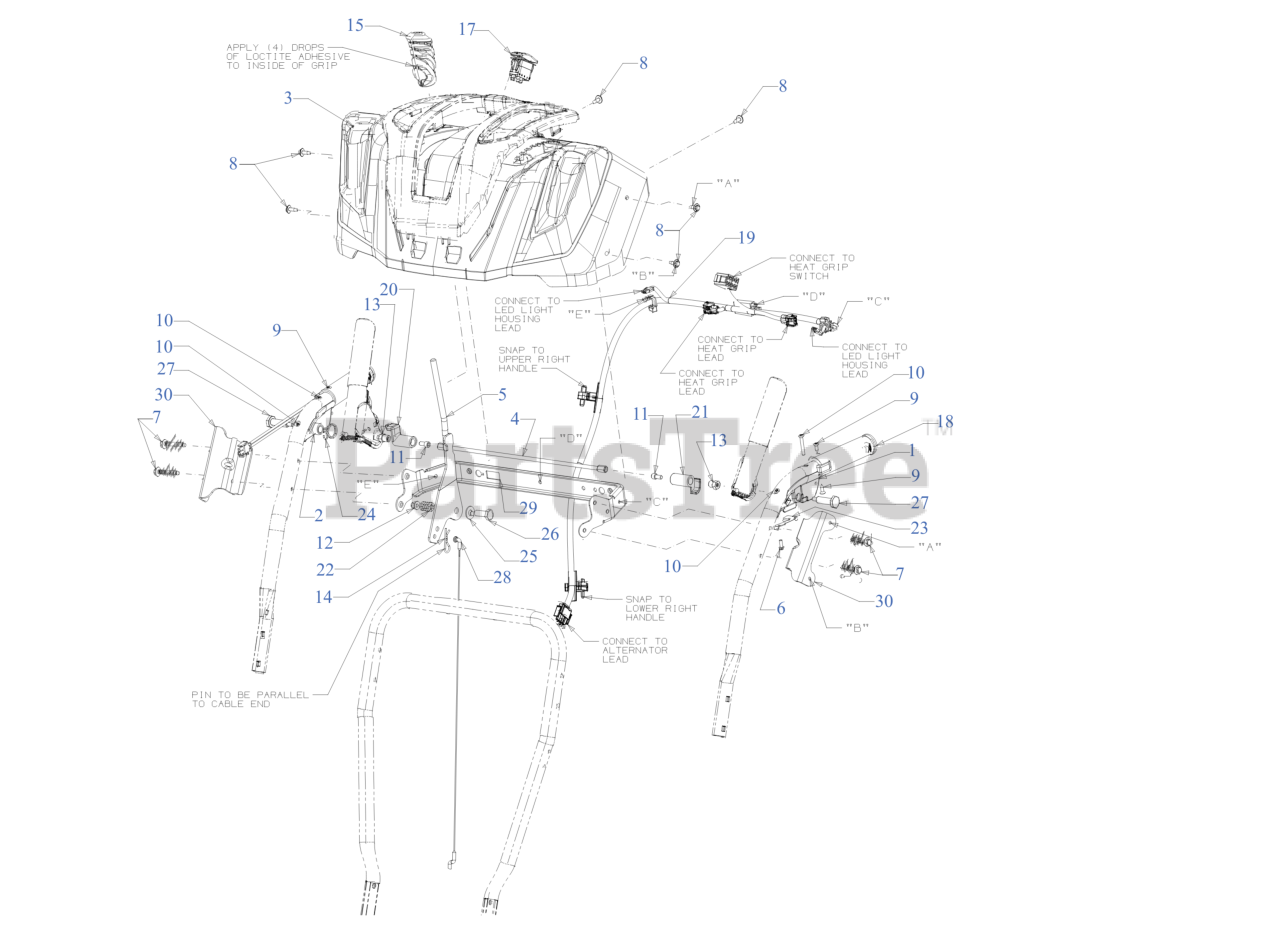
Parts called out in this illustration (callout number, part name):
1	CLUTCH LOCK HANDLE ASSEMBLY (LH)
2	CLUTCH LOCK HANDLE ASSEMBLY (RH)
3	HANDLE PANEL ASSEMBLY
5	SPEED SHIFT CONTROL (POWDER BLACK)
6	SCREW #8-16 x .50
7	SCREW 1/4-20 x 1.625
8	SCREW M6-1 x .625
9	SCREW-AB #12-24 x .625
10	SCREW #10-24 x 1.375
11	SCREW 1/4-20 x .50
12	FLANGE LOCK NUT
13	HEX NUT W/PATCH
14	INTERNAL COTTER PIN
15	PTO HANDLE GRIP .355 ID
17	HEATED GRIP SWITCH
18	HEATED GRIP
19	HARNESS (TWO HEADLIGHT)
21	CLUTCH LOCK CAM
22	COMPRESSION SPRING
23	CLUTCH SPRING
24	TORSION SPRING
25	FLAT WASHER .40X.88X.060
26	SHOULDER SCREW
27	SHOULDER SCREW .437 x 1.345 1/4-20
28	SPEED SELECTOR CABLE (PLASTIC)
29	HANDLE SUPPORT BRACKET (POWDER BLACK)
30	HANDLE PANEL BRACKET (POWDER BLACK)
